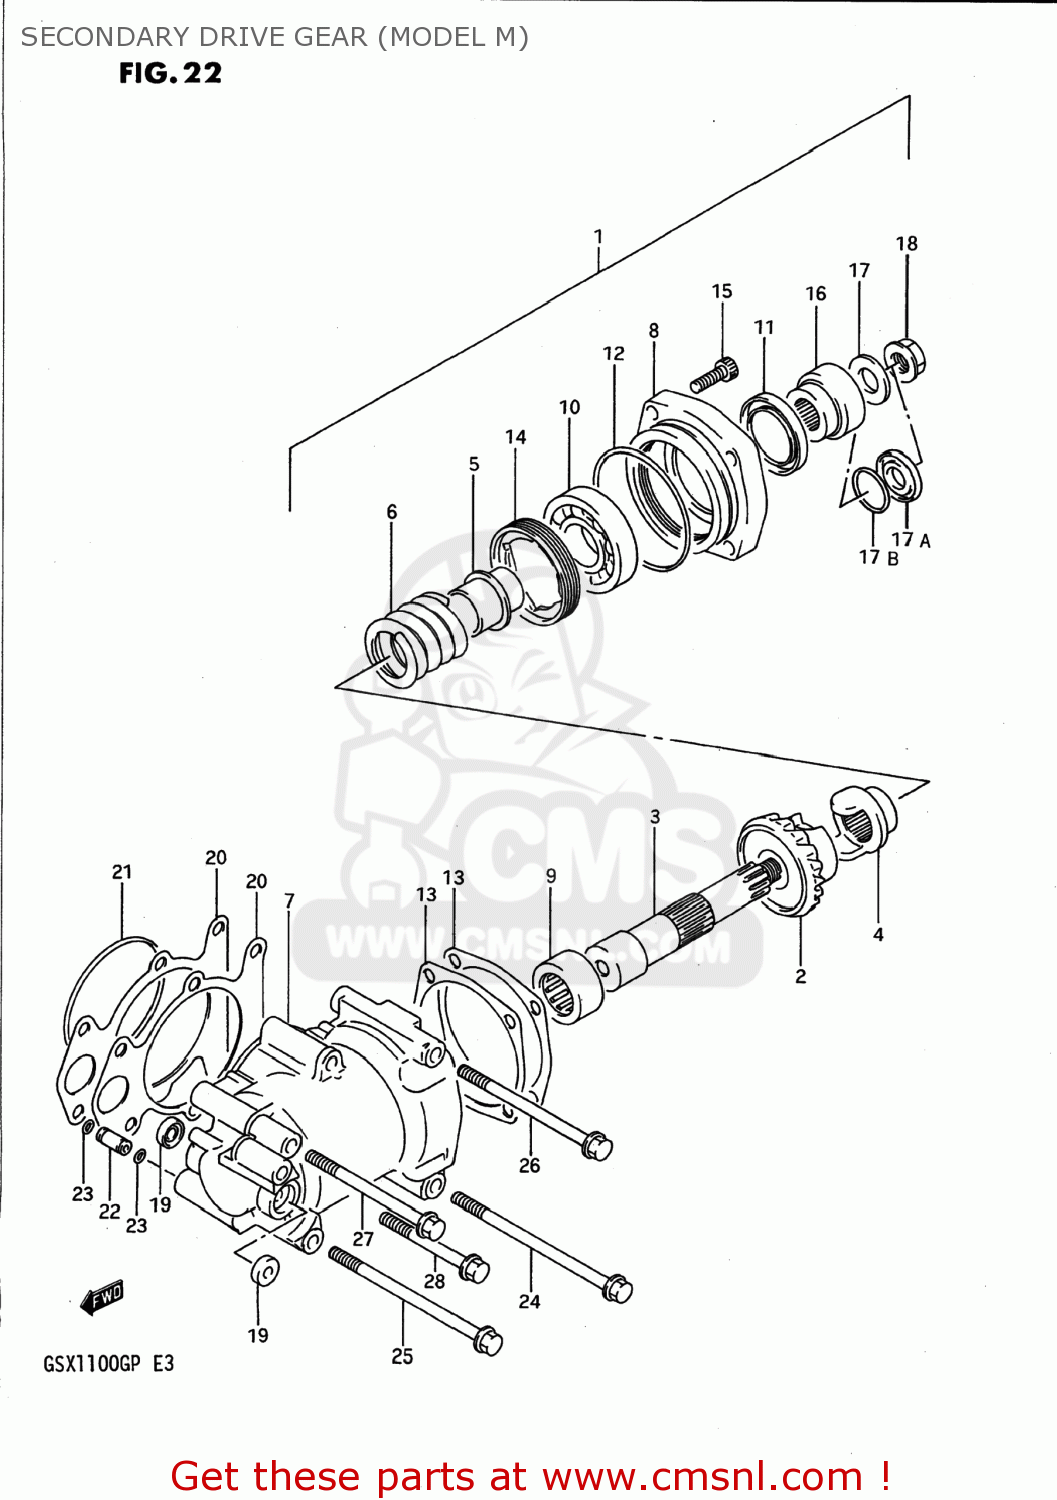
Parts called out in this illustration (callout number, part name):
1	GEAR & CASE SET,SECONDARY BEVEL
2	GEAR,SECONDARY DRIVEN
3	SHAFT,SECONDARY DRIVEN
4	DOG,OUTPUT CAM
5	STOPPER,CAM SPRING
6	SPRING
7	CASE COMP,SECONDARY GEAR
8	HOUSING,SECONDARY DRIVEN BEARING
9	BEARING(32X48X22)
10	BEARING(28X68X18)
11	SEAL,OIL(38X54X6)
12	O RING(D:3.7,ID:76.5)
13	SHIM,SECONDARY DRIVEN
14	STOPPER,SEC DRIVEN BEARING
15	BOLT
16	COUPLING,SECONDARY DRIVEN BELT
17	WASHER(16.5X36X4)
17A	WASHER
17B	O RING(D:2.4,ID:26.2)
18	NUT
19	SEAL,OIL(6X18X5)
20	SHIM,SECONDARY DRIVE NO.1
21	O RING(D:2.2,ID:88)
22	PIPE,SECONDARY CASE OIL
23	O RING(D:1.7,ID:6)
24	BOLT(8X125)
25	BOLT(8X120)
26	BOLT(8X105)
27	BOLT (8X95)
28	BOLT (8X70)
